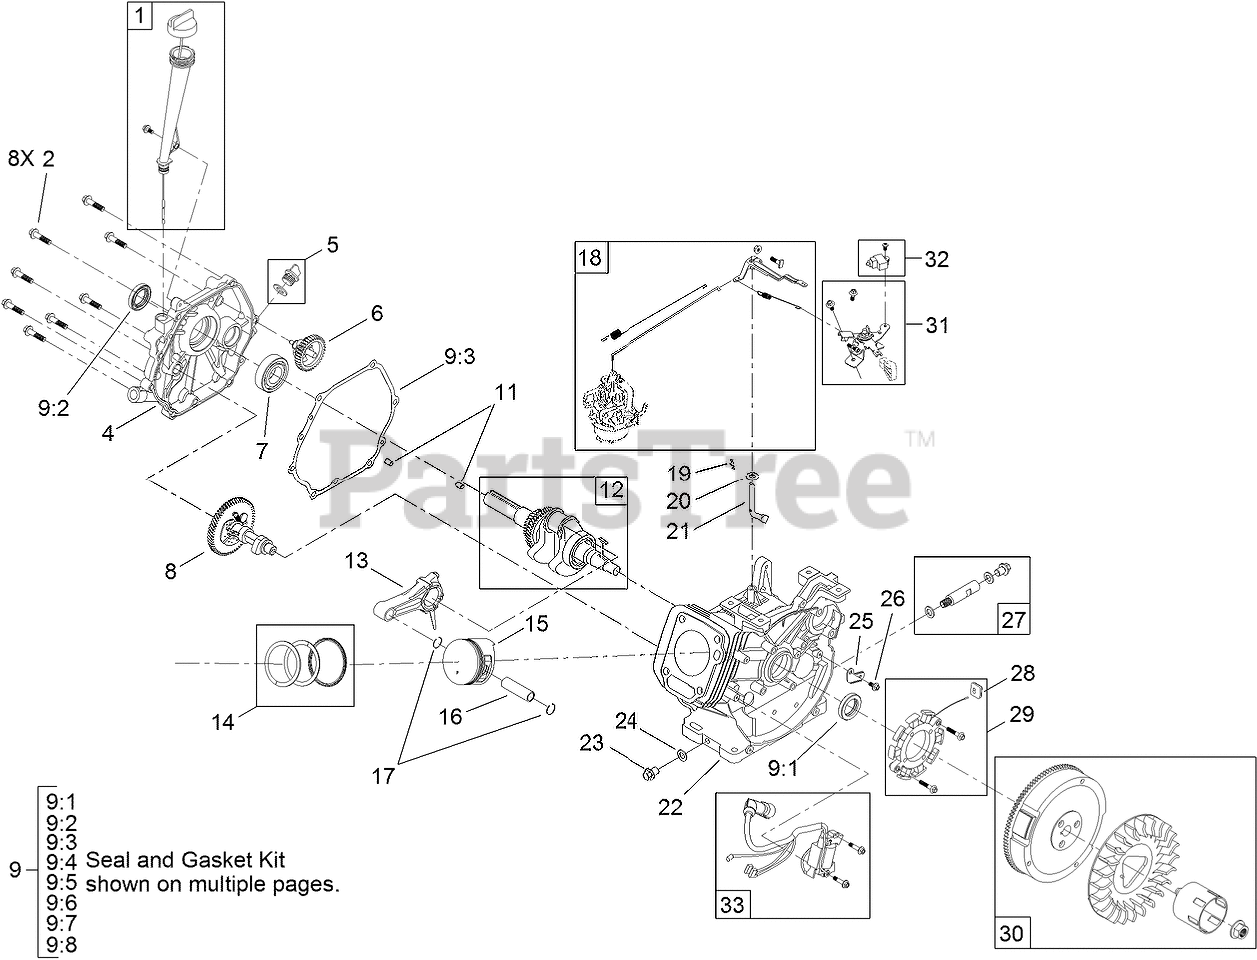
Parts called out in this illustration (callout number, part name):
1	OIL FILL KIT
2	SCREW-HHF
4	COVER-CRANKCASE
5	SUMP PLUG ASM
6	GOVERNOR GEAR ASM
7	BEARING-MAIN
8	CAMSHAFT ASM
9	SEAL AND GASKET KIT
9:1	Seal-Oil
9:2	Seal-Oil
9:3	GASKET-COVER, CRANKCASE
9:4	GASKET-HEAD, CYLINDER
9:5	GASKET-COVER, VALVE
9:6	Gasket-Exhaust
9:7	GASKET-CARBURETOR
9:8	GASKET-CARBURETOR
11	PIN-DOWEL
12	CRANKSHAFT ASM
13	CONNECTING ROD ASM
14	SET-RING, PISTON
15	PISTON
16	PIN-PISTON
17	CLIP-PIN, PISTON
18	COMPLETE GOVERNOR KIT
19	PIN-HAIR
20	WASHER-PLAIN
21	SHAFT-GOVERNOR
22	CRANKCASE
23	SCREW-HHF
24	WASHER-PLAIN
26	SCREW-HHF
27	DRAIN PLUG KIT
28	GROMMET-RUBBER
29	STATOR KIT
30	FAN AND FLYWHEEL KIT
31	THROTTLE CONTROL KIT
32	KILL SWITCH KIT
33	IGNITION MODULE KIT
